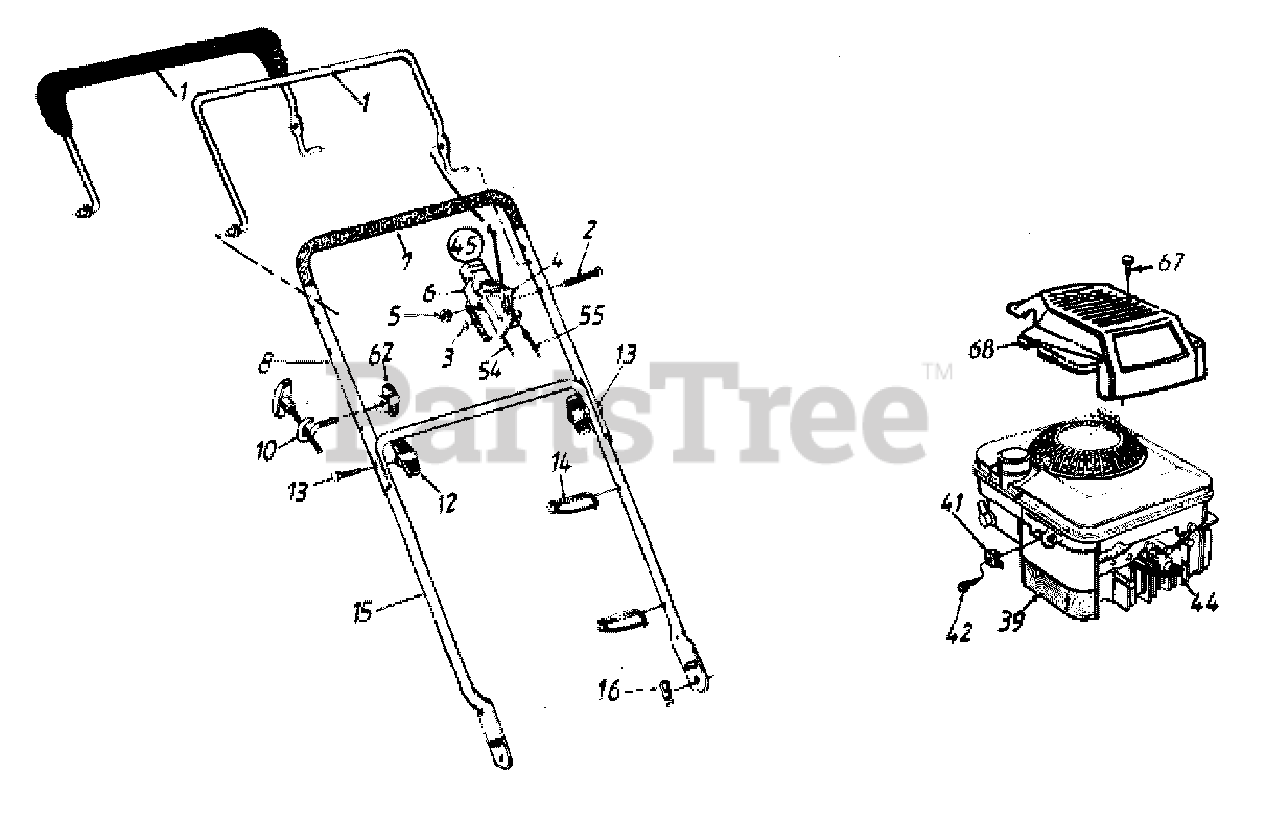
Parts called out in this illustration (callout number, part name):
1	Control Handle Ass'y.
2	Oval C-Sunk Screw
3	Spring Washer
4	Throttle Lever
5	Hex Lock Nut
6	Throttle Body
7	Foam Grip
8	Upper Handle
12	Hand Knob
13	Carriage Bolt
14	Cable Tie
15	Lower Handle
16	Hairpin Clip
39	Engine
41	Cable Clamp
42	Hex TT Screw #10-32 x .62"
44	Spark Plug Boot
45	Throttle Box Comp.
54	Throttle Cable
55	Control Cable
68	Engine Shroud
